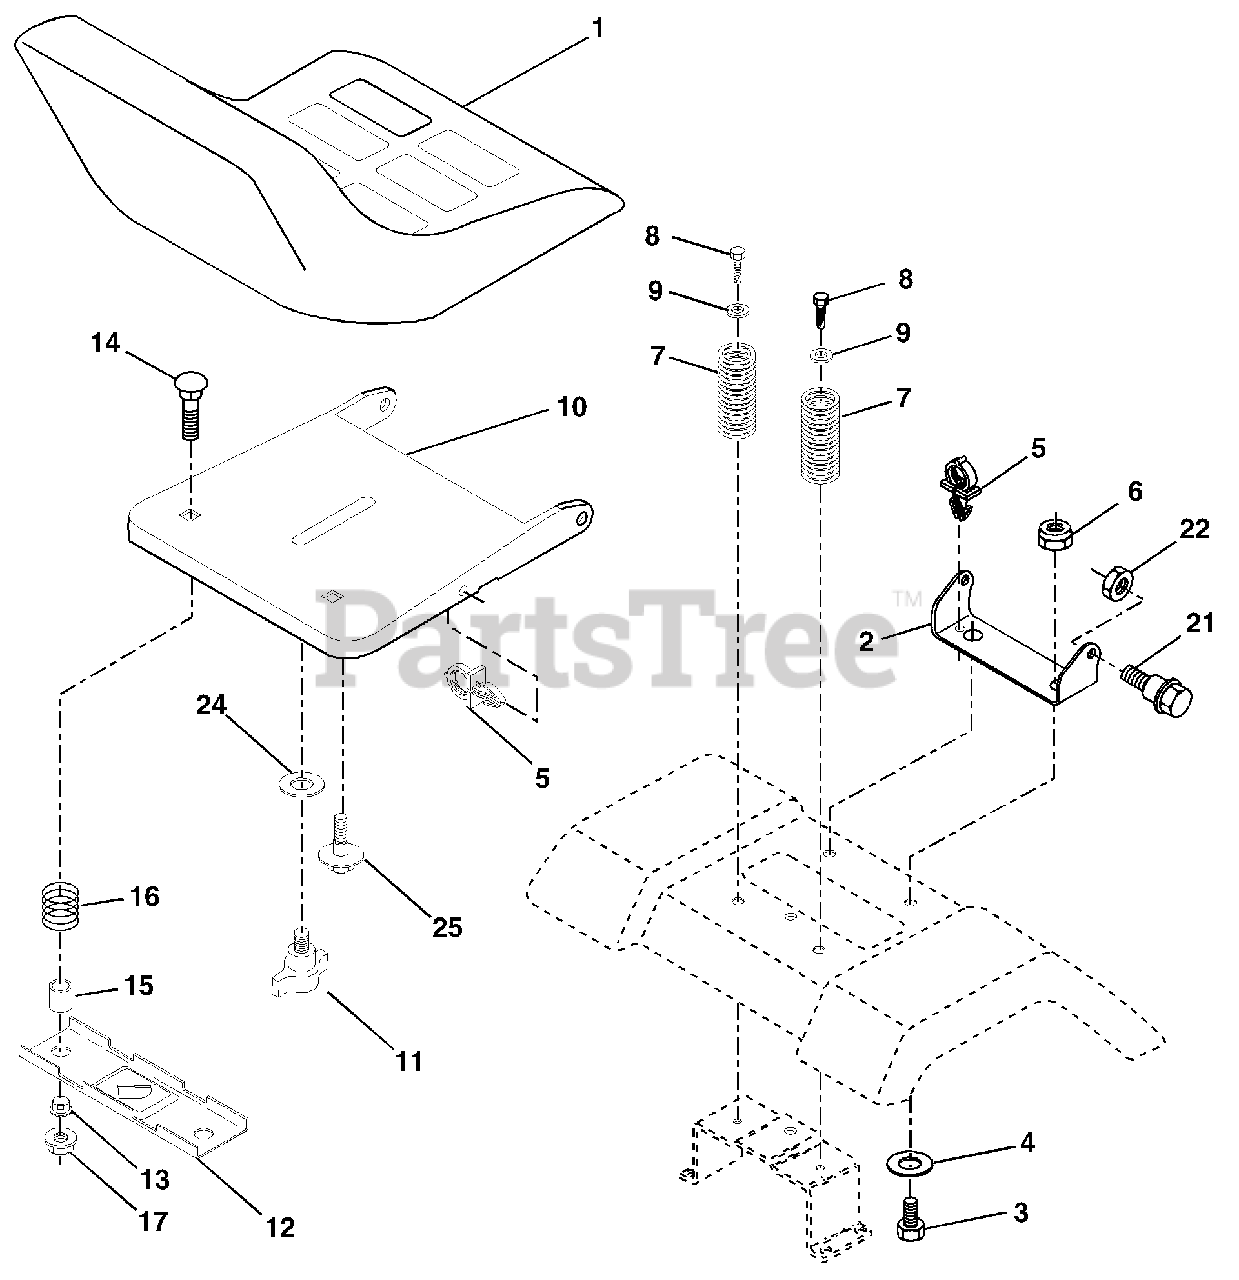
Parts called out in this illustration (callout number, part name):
1	Seat
2	Bracket Pivot Seat 8 720
3	Bolt Fin Hex 3/8-16 unc X 1
4	Washer 13/32 X 1 X 10 Ga
5	Clip Push-In
6	Nut Hex w/Ins. 3/8-16 Unc
7	Spring Seat Cprsn 2 250 Blk Zi
8	Screw 3/8-16 X 1
9	Washer 13/32 X 1 X 14 Ga.
10	Pan Seat
12	Bracket Mounting Switch
13	Bushing Snap Blk Nyl 50 Id
14	Bolt Rdhd Sqnk 1/4-20x1-1/2
15	Spacer Split 28x 96 Yel Zinc
16	Spring Cprsn 1 27 Blk Pnt
17	Nut Lock 1/4 Lge Flg Gr 5 Zinc
21	Bolt Shoulder 5/16-18 Unc-2A
22	Nut Hex Lock W/Ins 5/16-18
24	Washer 17/32 X 1-3/16 X 12 Ga.
25	Bolt Shoulder 5/16-18 X 62
